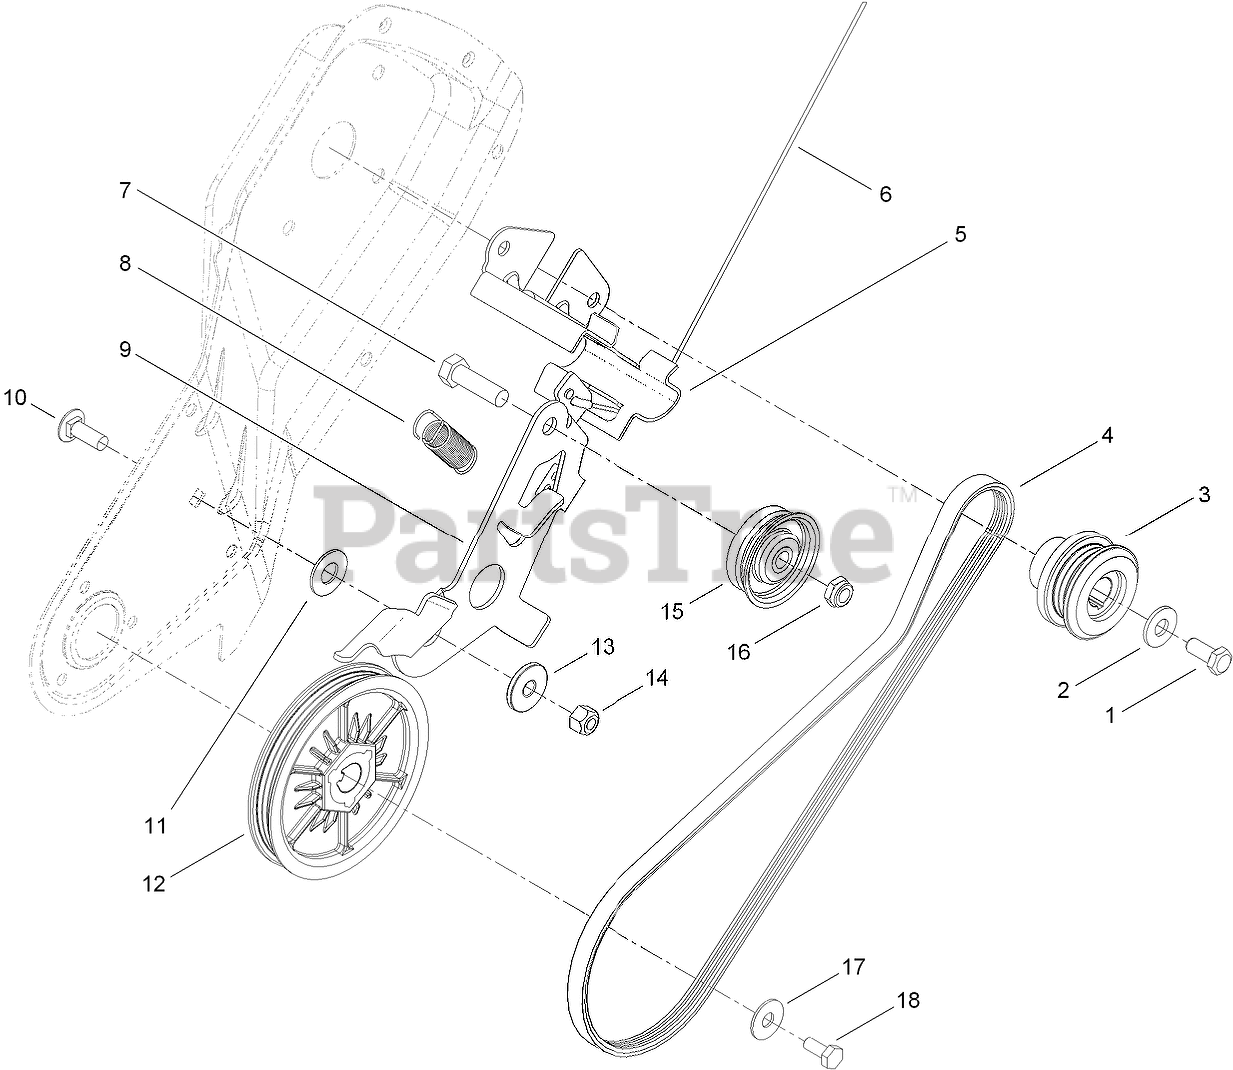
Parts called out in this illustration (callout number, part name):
1	SCREW-HH
2	WASHER-FLAT
3	PULLEY-ENGINE
4	BELT-V, RIBBED
5	GUIDE-BELT
6	CABLE-CLUTCH
7	SCREW-HH
8	SPRING-BRAKE
9	ARM-IDLER
10	BOLT-CARR
11	WASHER
12	ROTOR PULLEY ASM
13	BUSHING-IDLER
14	NUT-LOCK, NI
15	PULLEY-IDLER
16	NUT-LOCK, NI
17	WASHER-BELLEVILLE
18	SCREW-HH
